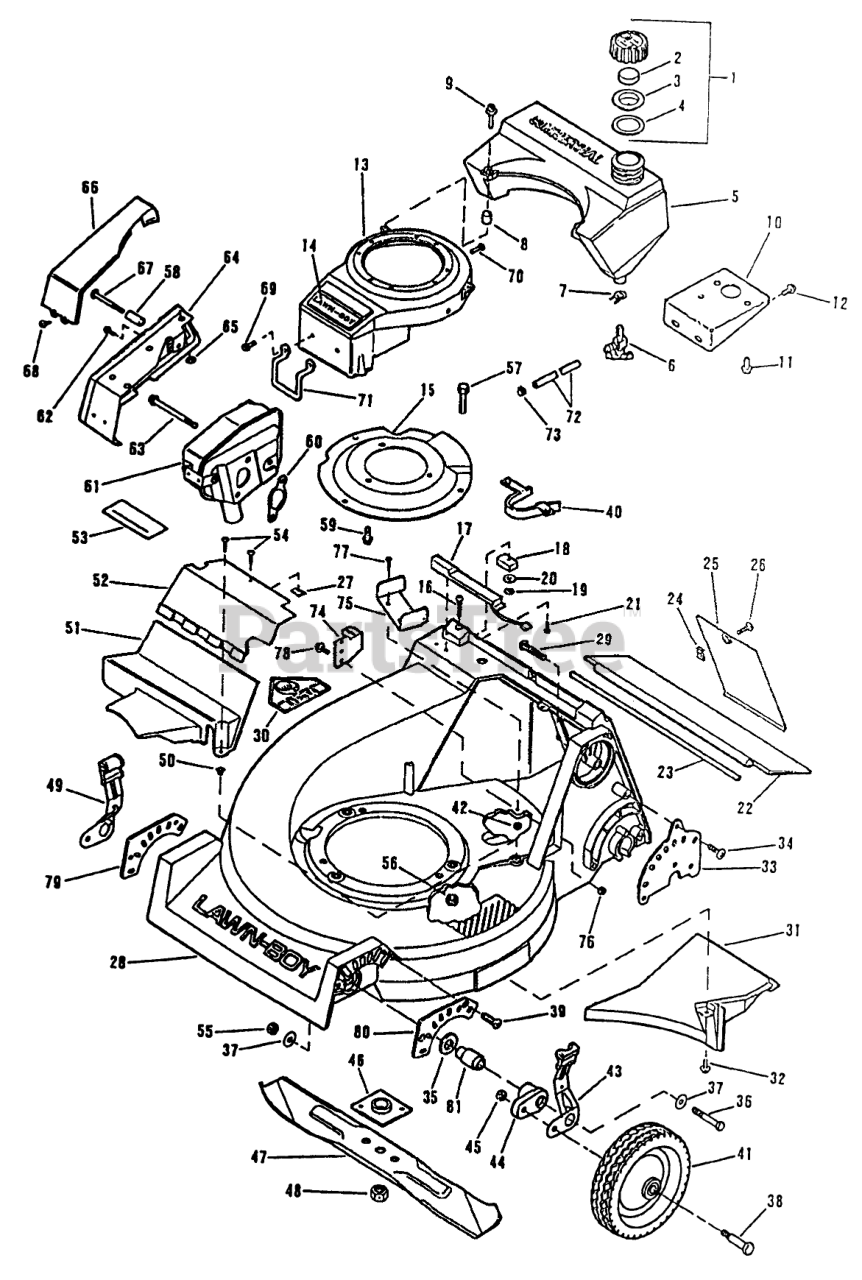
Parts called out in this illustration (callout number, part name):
1	CAP AY - F/OIL SM
2	BAFFLE - FOAM SM
3	Cover
4	GASKET-FUELCAP SM
5	Fuel Tank
6	VALVE&SCREEN SM
7	CLAMP - HOSE S
8	Spacer
9	SCREW - SEMS SM
10	Fuel Tank Mounting Bracket
11	SCREW-HH
12	SCREW HEX WASH SM
13	SHROUD & APPL S
14	APPLIQUE SM
15	PLATE SM
16	SCREW
17	SWITCH ASSEMBLY
18	MAGNET ASSY
19	NUT
20	LOCKWASHER #10
21	SCREW-STAINLESS
22	Trailing Shied
23	ROD ADVANCE
24	SPEED NUT LARSON
25	DOOR-ACCESS ELECT.
26	SCREW-CROSS RECESS
27	NUT-SPEED
28	Housing Assembly
29	BOLT - RIBBED NECK
30	Decal
31	CHUTE BAFFLE NYL
32	Screw
33	PLATE HGT CMS
34	SCREW-BUTTON HEAD
35	WASHER, PLAIN
36	SCREW - HEX HEAD
37	WASHER PLAIN
38	BOLT-WHEEL-SHOULDR
39	SCREW,FLAT HEAD
40	GUIDE BELT SM
41	WHEEL/TIRE ASM
42	NUT C/LOCK E
43	KNOB & SPRING CMS
44	ARM HGT ADJ BLACK
45	NUT-JAM, LOCKING
46	PLATE AND COLLAR ASM
47	21" Blade
48	NUT-BLADE
49	KNOB & SPRING CMS
50	NUT-CLIP
51	COVER-DRIVE-LOWER
52	COVER-UPPER
53	DECAL
54	SCREW S
55	NUT
56	NUT-LOCK F
57	SCREW-HH
58	SPACER S
59	SCREW SM
60	GASKET - EXH SM
61	Muffler
62	SCREW S
63	SCREW-SEMS
64	GUARD AY-MUFFLER
65	NUT-PUSH
66	COVER-MUFFLER
67	SCREW SM
68	SCREW SM
69	SCREW-HEX FL SM
70	SCREW SM
71	GUARD-SPK.PLUG.SM
72	GAS LINE S
73	HOSE CLAMP SM
74	ANCHOR-CABLE
75	BELT GUIDELB
76	LOCKNUT E
77	SCREW M-EX 5/24
78	Screw
79	RH PLATE HEIGHT ADJ LB
80	LH PLATE HEIGHT ADJ LB
81	BUSHING,FRT HT ADJ
